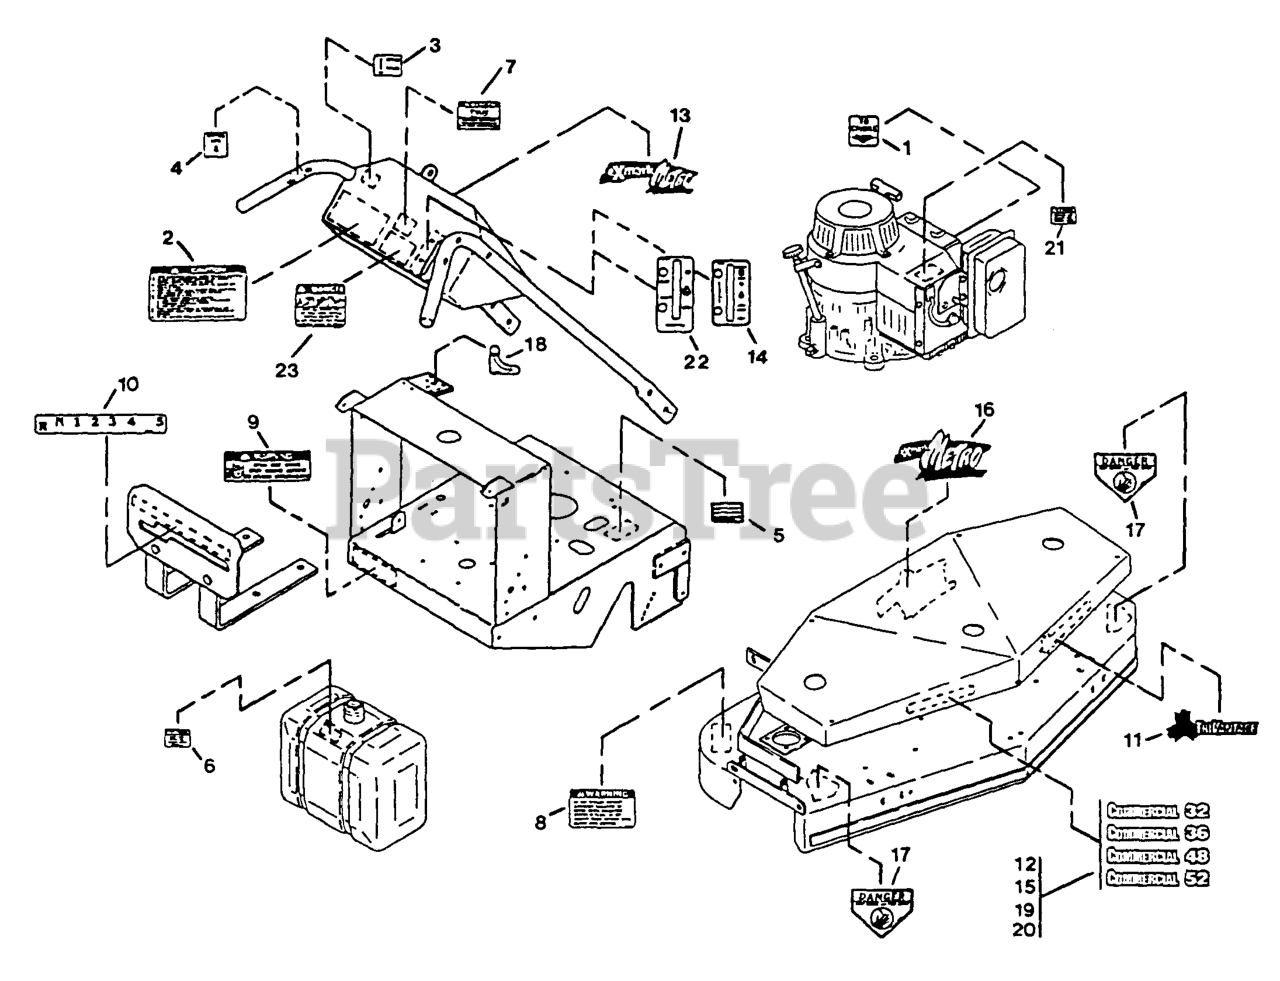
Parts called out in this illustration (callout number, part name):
2	LABEL,INSTRUCTION
3	DECAL,CUTTER BLADE
4	DECAL,NEUTRAL LOCK
8	DECAL-WARNING, DISCHARGE
9	DECAL,BELT DRIVE
10	DECAL,SHIFTER
12	DECAL,COMMERCIAL 32
15	DECAL,COMMERCIAL 36
17	DECAL-DANGER
19	DECAL,COMMERCIAL 48
20	DECAL,COMMERCIAL 52
23	DECAL-DANGER
